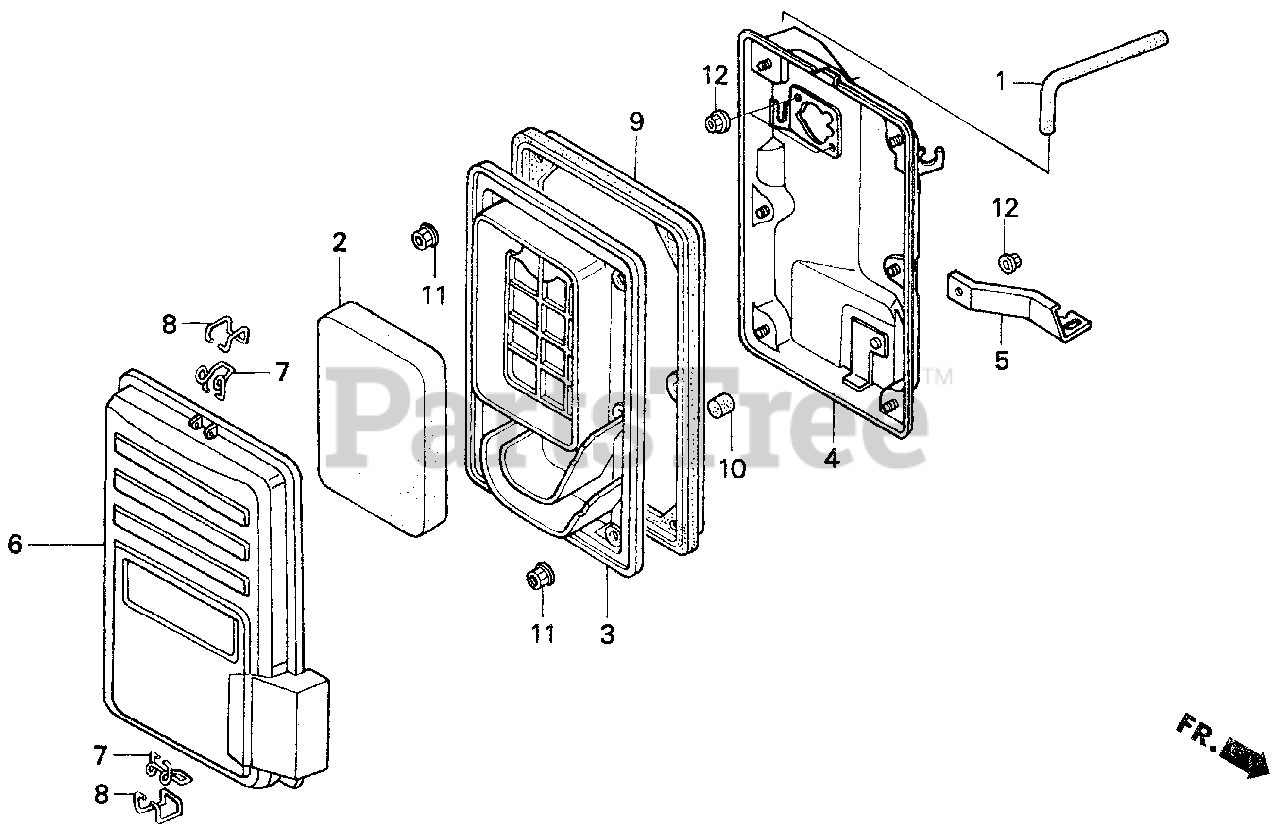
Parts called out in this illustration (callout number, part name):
1	TUBE, BREATHER
2	ELEMENT, AIR CLEANER
3	SEPARATOR, AIR CLEANER
4	HOUSING, AIR CLEANER
5	STAY, AIR CLEANER
6	COVER, AIR CLEANER
7	CLIP A, AIR CLEANER WIRE
8	CLIP B, AIR CLEANER WIRE
9	SEAL, AIR CLEANER
10	FILTER, DRAIN TUBE
11	NUT, FLANGE (5MM)
12	NUT, FLANGE (6MM)
